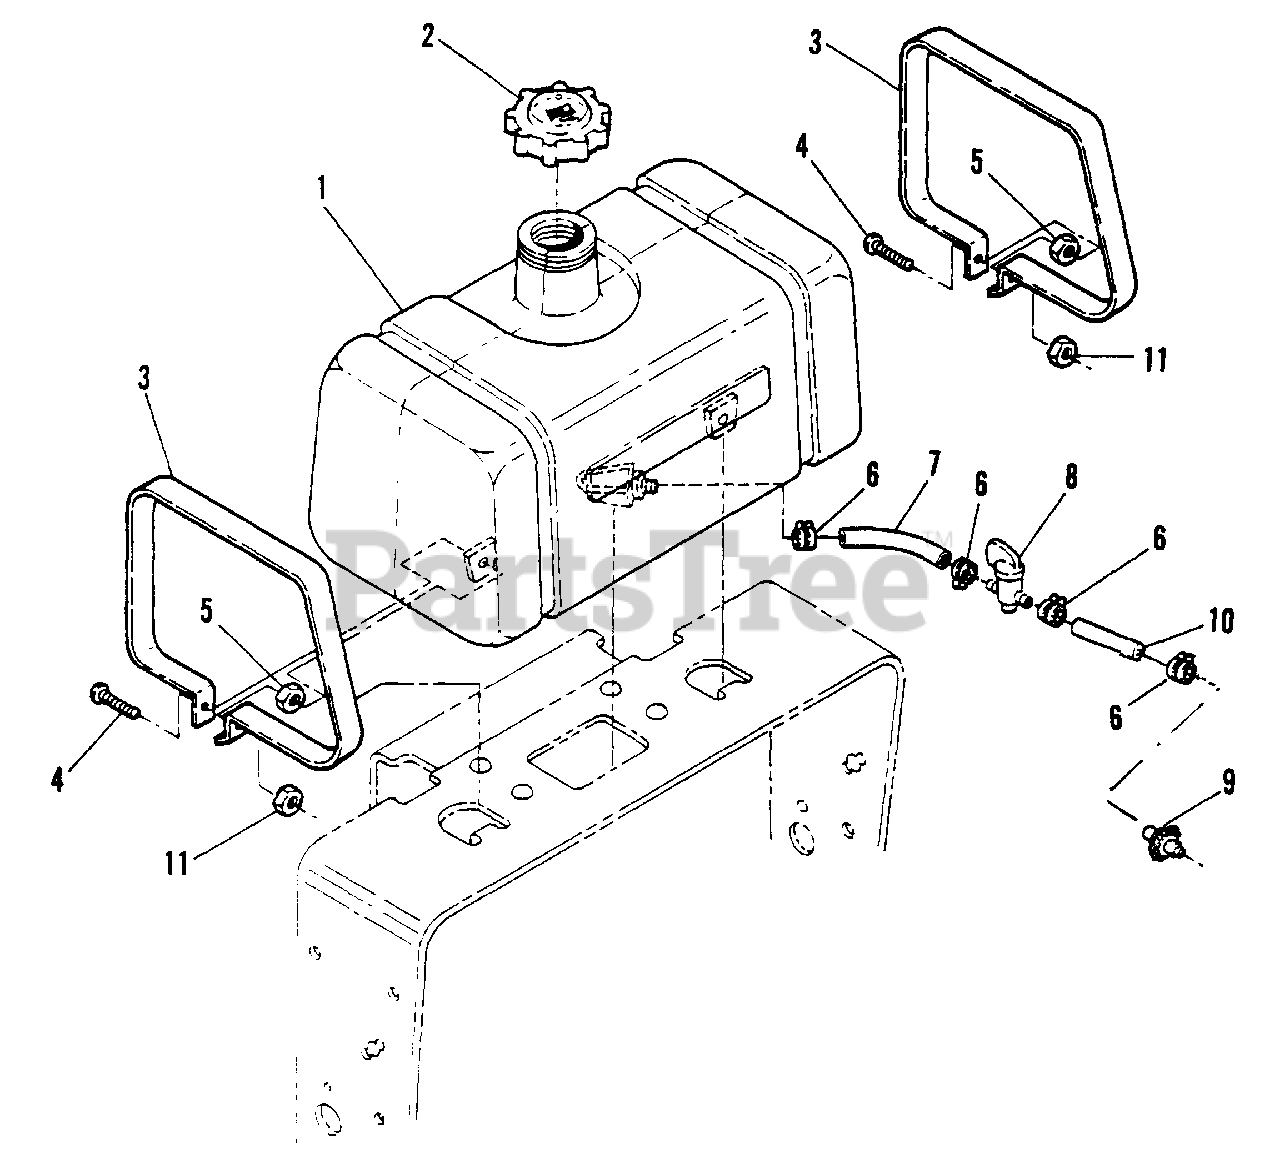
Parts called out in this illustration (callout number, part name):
1	TANK, Fuel
2	GAS CAP
3	STRAP, Tank
4	SCREW, Machine Head Phillips, #10 - 24 x 2
5	NUT, Keps #10 - 24
6	HOSE, Clamp
7	FUEL LINE, 10"
8	FUEL SHUT-OFF VALVE
9	FILTER, In-Line
10	FUEL LINE, 3-1/2"
11	NUT, #10 - 24 Lock
